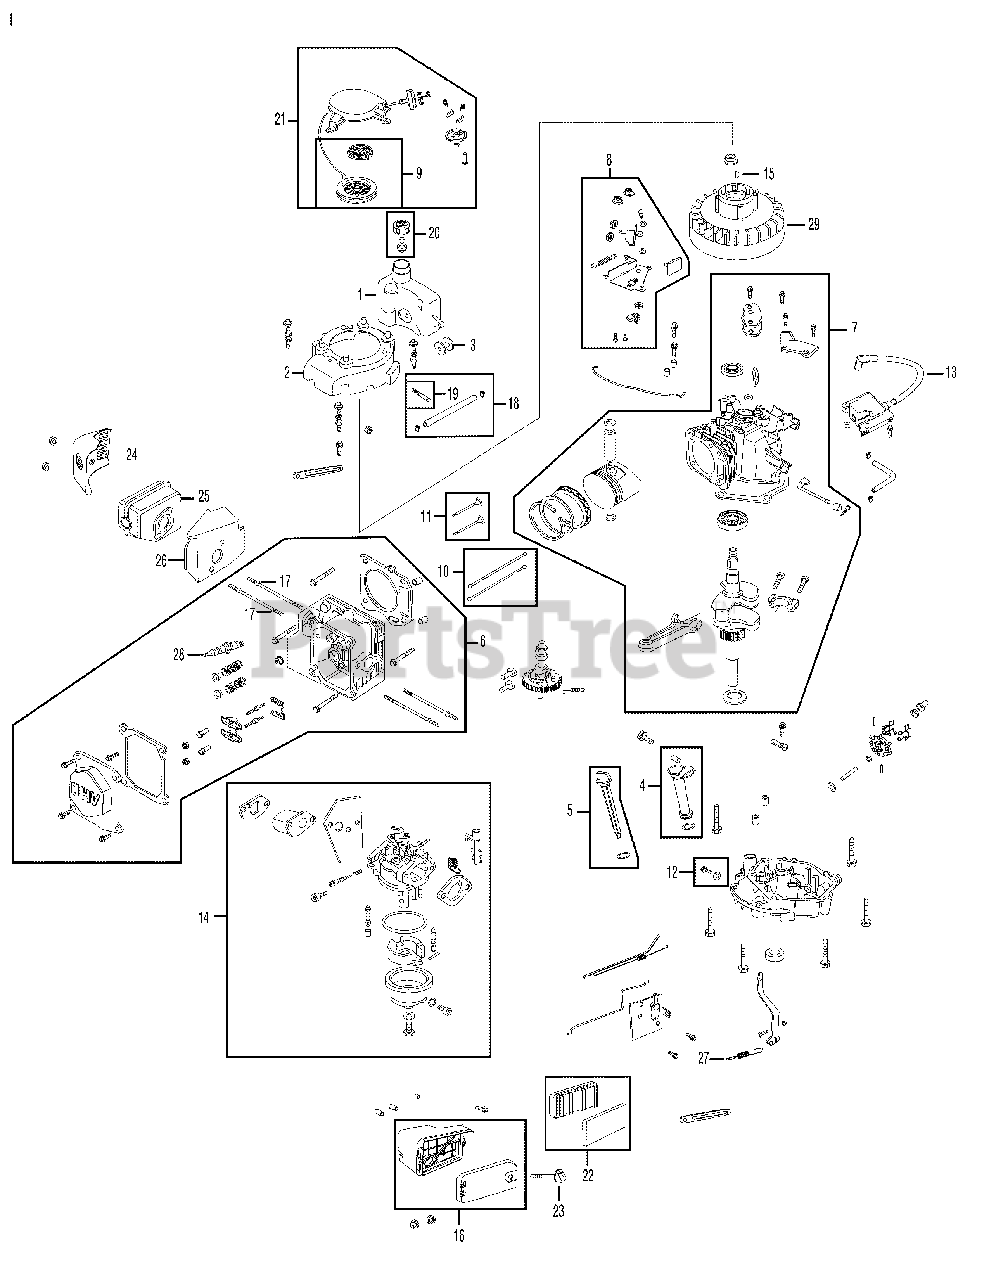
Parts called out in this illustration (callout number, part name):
1	Fuel Tank
2	Flywheel Shroud
3	Rubber Fuel Tank Mounting Washer
4	Oil Filler Tube Assembly
5	Dipstick Assembly
6	Cylinder Head Complete
7	Short Block Assembly
8	Stop Switch and Brake Assembly
9	Recoil Spring and Pulley Assembly
10	Push Rod Kit
12	Oil Drain Plug and Washer Assembly
13	Ignition Coil
14	Carburetor Assembly
15	Flywheel Key
16	Air Cleaner Housing Assembly Complete
17	Muffler Stud Assembly
18	Fuel Line Kit - Inc. hoses, clamps & filter
19	Fuel Filter
20	Fuel Cap Assembly
21	Recoil Starter Assembly
22	Air Cleaner Kit
23	Air Cleaner Thumb Screw
24	Muffler Guard
26	Muffler Gasket /Heat Shield
27	Governor Return Spring
28	Spark Plug
